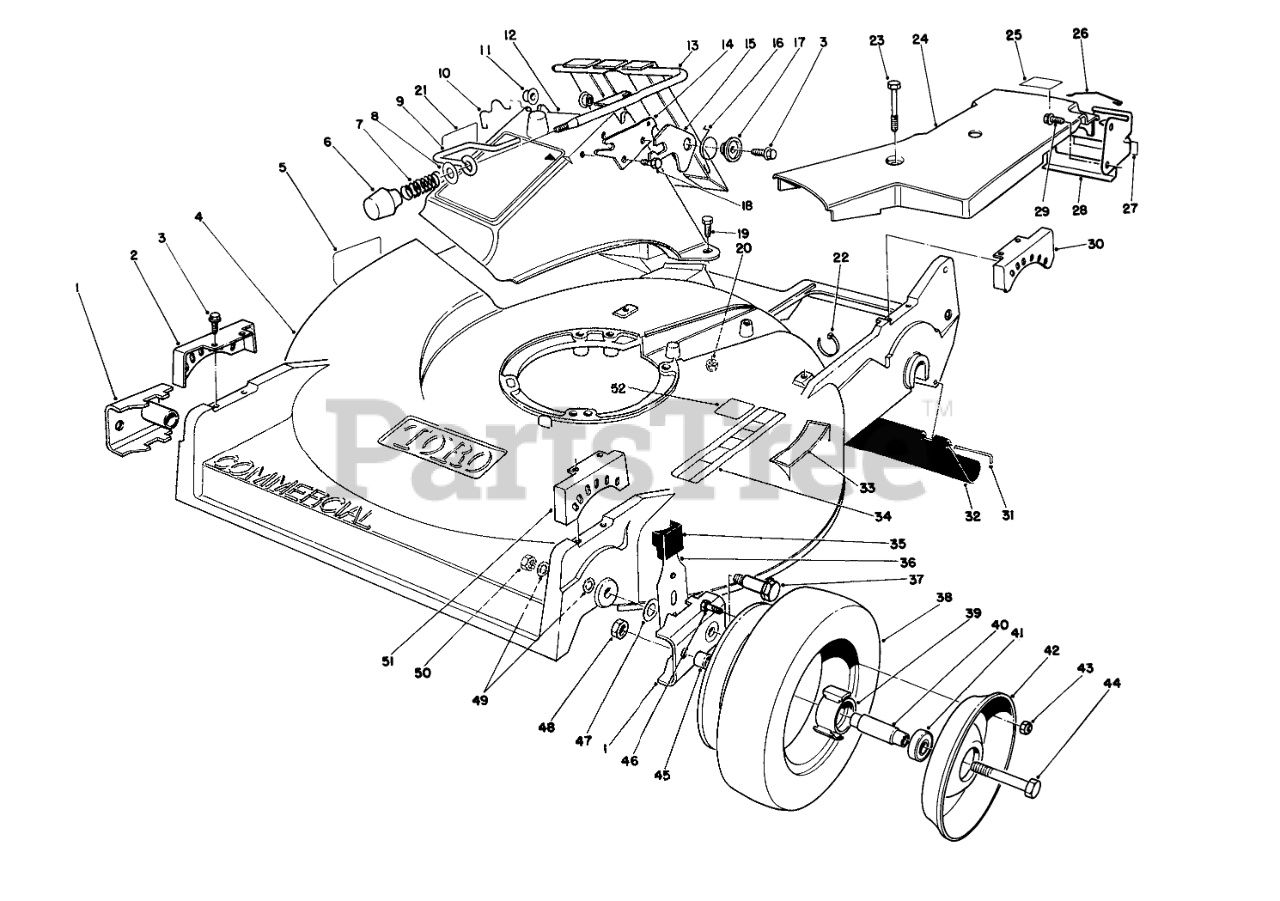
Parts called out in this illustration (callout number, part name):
1	ARM-PIVOT, FRONT
2	QUADRANT-FRONT, RH
3	SCREW-HWHTF
4	Housing-Commercial (Incl. Ref. #5, 33 & 34)
5	Decal Danger
7	COMPRESSION SPRING
8	WASHER-FLAT
9	DOOR LATCH
10	DOOR RETAINER
11	BUSHING-NYLON
12	DISCHARGE CHUTE B
13	DOOR & HANDLE WA
14	DOOR LATCH PLATE
15	SAFETY LATCH
16	TORSION SPRING
17	DOOR SPACER
18	SCREW-HWH
19	SCREW-HH
20	NUT-LOCK, NI
21	DECAL - DANGER
22	TIE-CABLE
23	SCREW-HHFTF
24	COVER-BELT
25	Label-Grease
26	RETAINER-CABLE
27	DECAL-POSITION, GEAR
28	BRKT-TRACTION ADJ.
29	SCREW-HWHTF
30	QUADRANT-REAR, LH
31	ROD-SHIELD
32	SHIELD-TRAILING
33	DECAL - STEP PAD INT'L
34	Decal-Safety Instructions
35	KNOB-ARM
36	FRONT SPRING ARM ASM
37	WHEEL BOLT
39	HUB-BEARING
40	SPACER-BEARING
41	BEARING-WHEEL
42	Wheel-Half
43	NUT-LOCK, NI
44	SCREW-HH
45	SPACER-WHEEL
46	SCREW-HH
47	WASHER-THRUST
48	NUT-LOCK, CONE
49	WASHER
50	Nut
51	QUADRANT-FRONT, LH
52	Decal-Noise
